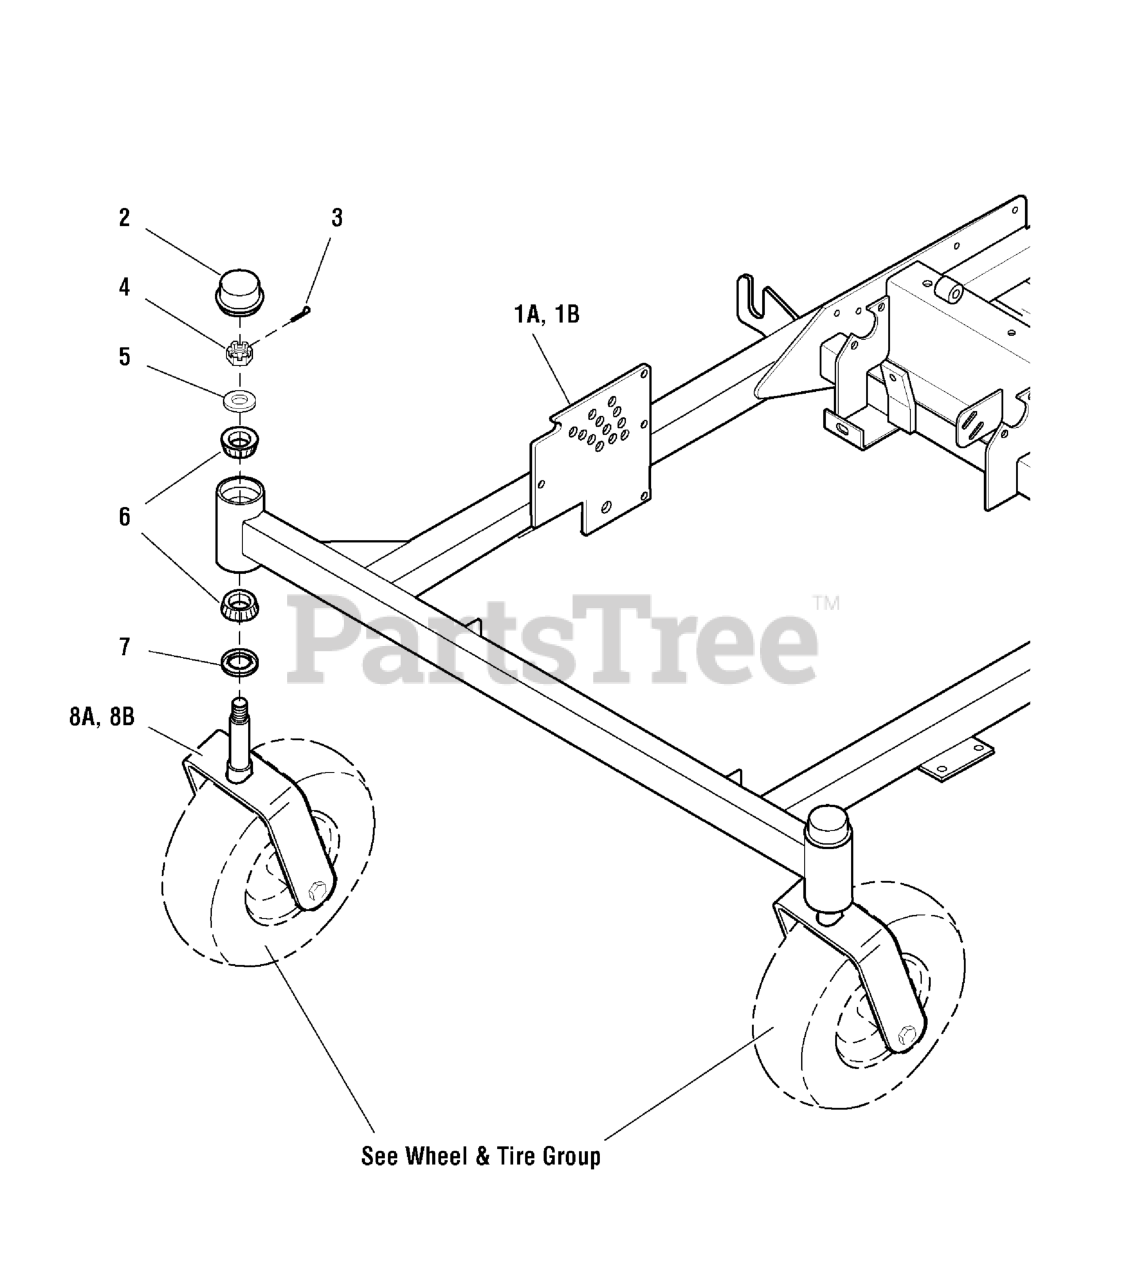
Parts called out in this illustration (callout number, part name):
1A	61" MAIN FRAME
1B	61" MAIN FRAME
2	CAP
3	PIN, COTTER, 1/8 X 1-1/4
4	NUT, HEX SLOTTED, 3/4-16
5	WASHER, 3/4 SAE
6	BEARING, TAPERED ROLLER
7	SEAL, GREASE
8A	CASTER YOKE
8B	CASTER YOKE
